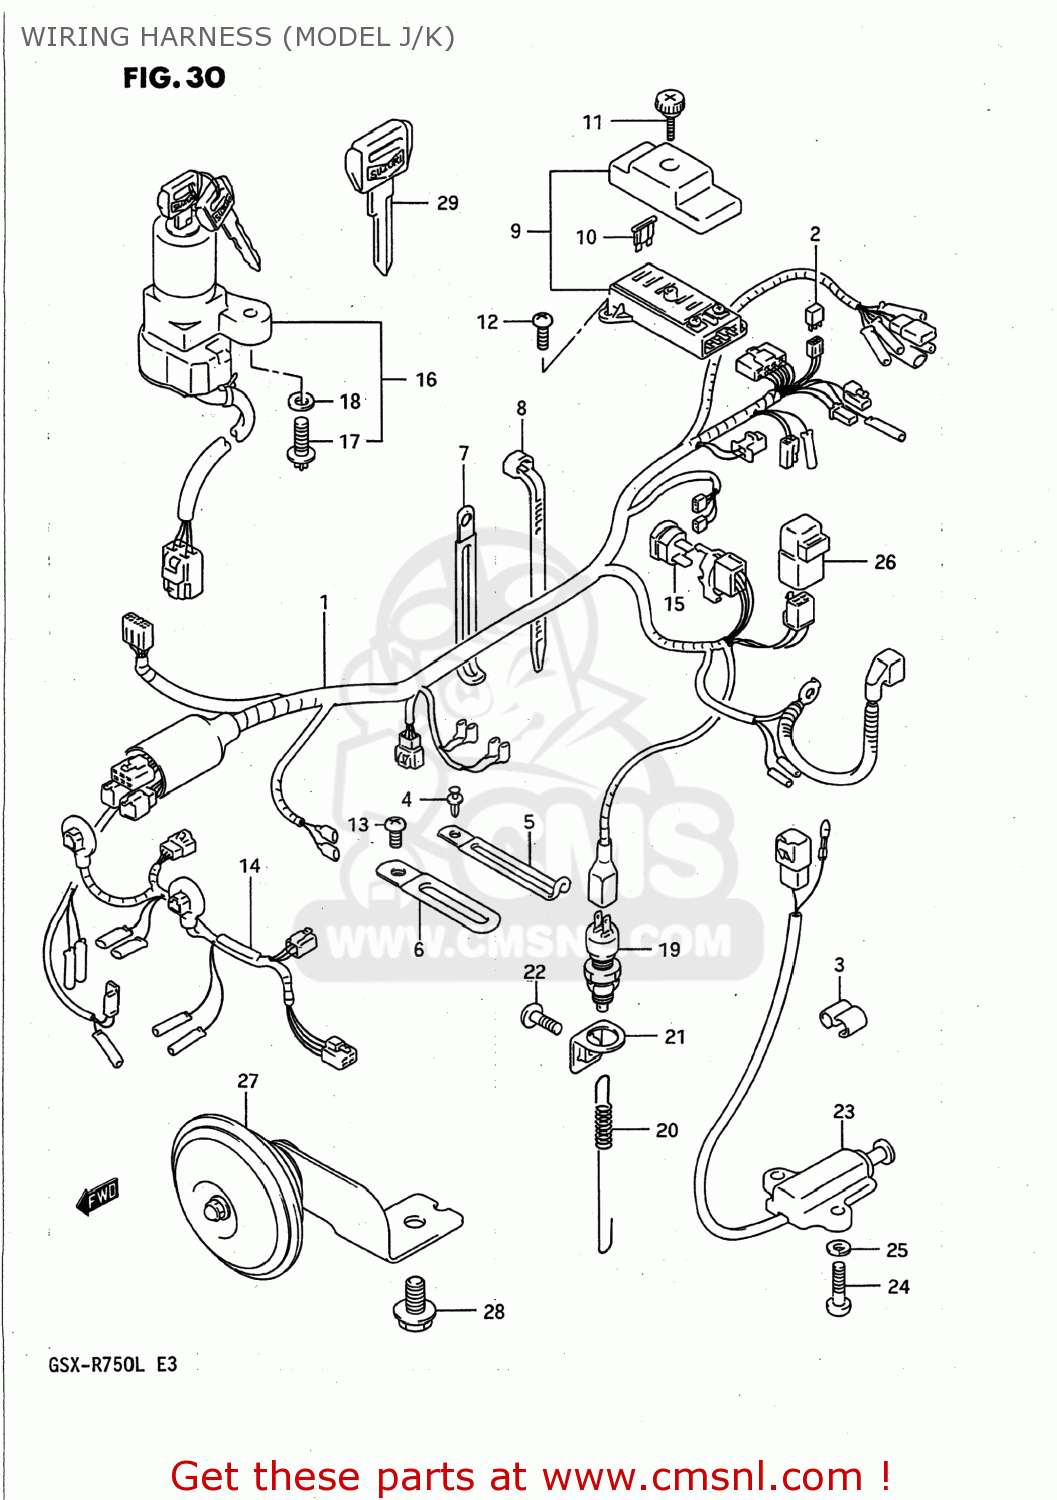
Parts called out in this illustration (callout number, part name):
1	HARNESS,WIRING
2	DIODE(STANLEY DE8804)
3	CLIP
4	CLIP
5	CLAMP
6	CLAMP
7	CLAMP
8	CLAMP(L:125)
9	BOX ASSEMBLY,FUSE
10	FUSE(10A)
11	SCREW,FUSE BOX
12	SCREW
13	SCREW
14	WIRE
15	BREAKER ASSY,CIRCUT
16	LOCK ASSEMBLY,STEERING
17	SCREW(6X18)
18	WASHER
19	SWITCH ASSY,STOP LAMP
20	SPRING
21	BRACKET,STOP LAMP SWITCH
22	SCREW(6X12)
23	SWITCH ASSEMBLY,SIDE STAND
24	SCREW
25	WASHER,LOCK
26	RELAY ASSEMBLY
27	HORN ASSEMBLY
28	BOLT 8X12
29	KEY,BLANK
